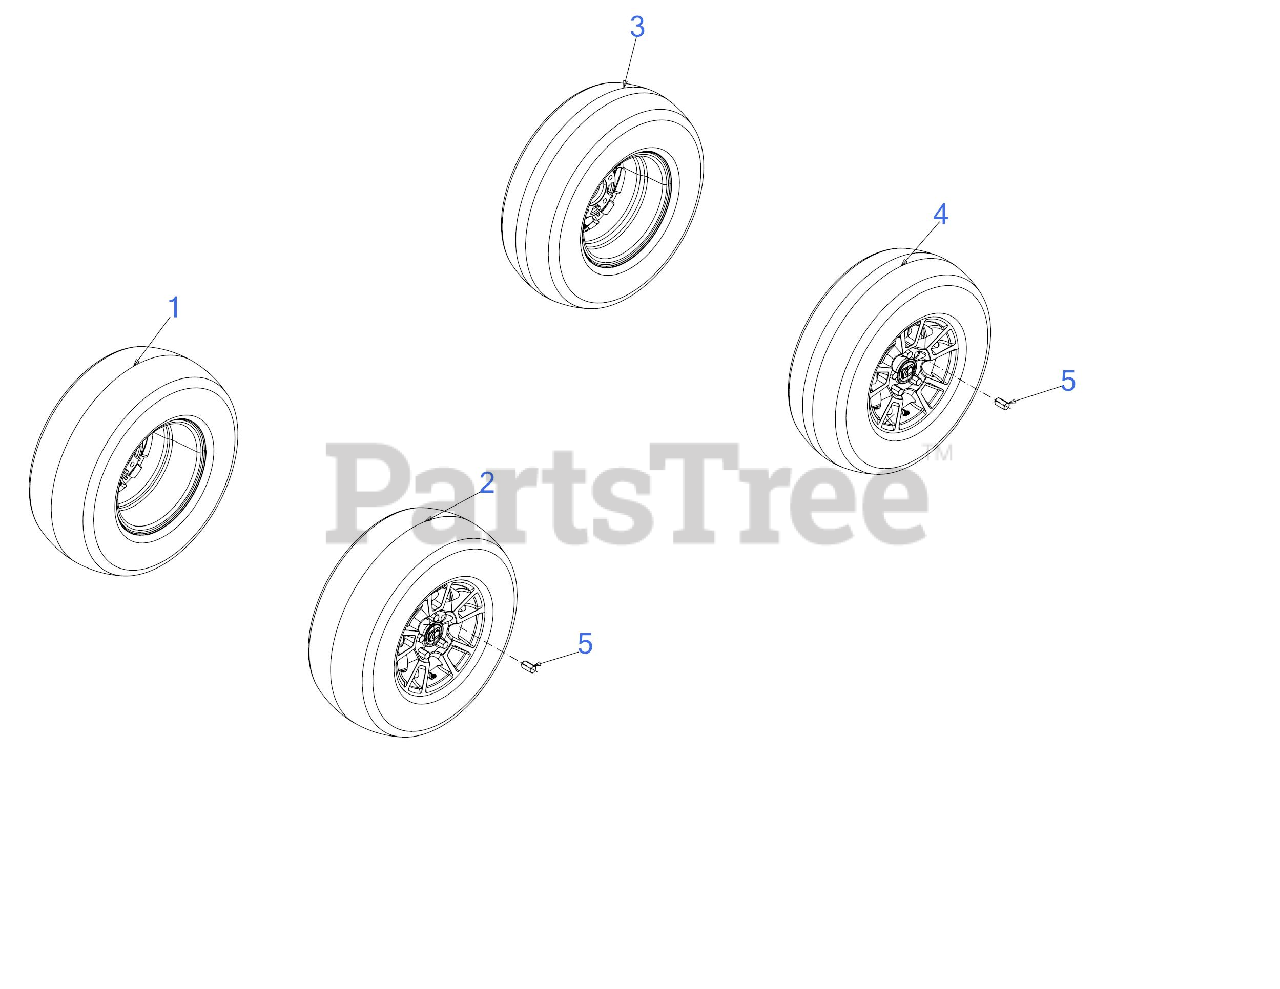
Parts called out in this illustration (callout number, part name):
1	WHEEL ASSEMBLY (LH) (24 x 9-12)
2	WHEEL ASSEMBLY (RH) (24 x 9-12)
3	WHEEL ASSEMBLY (LH) (24 x 8-12)
4	WHEEL ASSEMBLY (RH) (24 x 8-12)
5	CHROME LUG NUT
